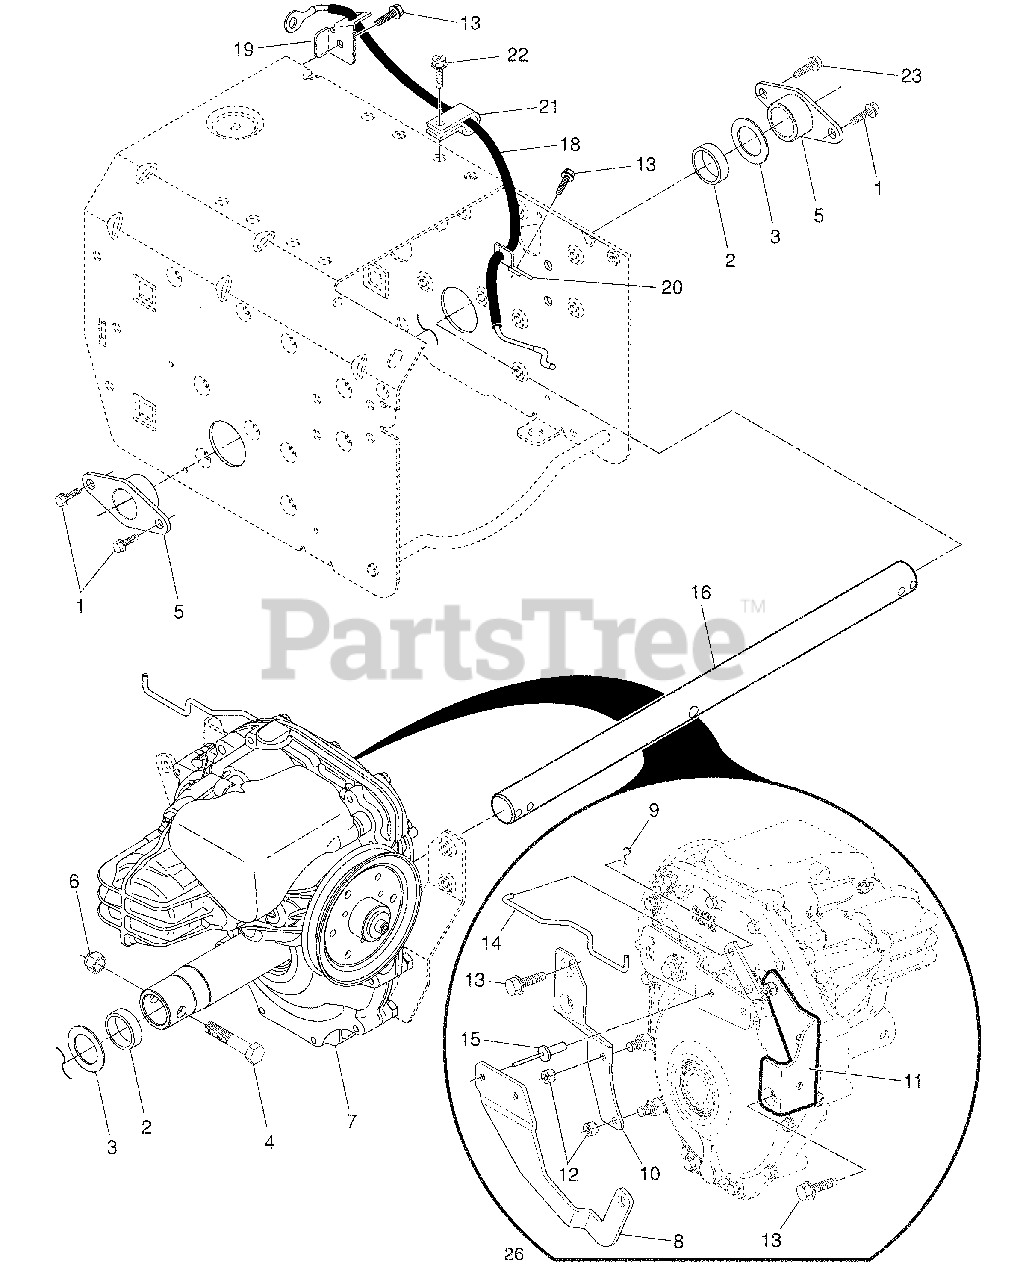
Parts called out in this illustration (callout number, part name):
1	Screw, Hex Head 5/16-18 x 3/4
2	Spacer, Axle
3	Washer, Thrust
4	Screw, Cap, Hex Head 3/8-16 x 2
5	Bearing, Axle
6	Nut, Hex, Centerlock 3/8-16
7	Transmission Assembly
8	Speed Control Arm, Hydro
9	Retainer Clip
10	Torque Strap
11	Bracket, Anti-Rotate
12	Nut, Hex, Nylock 1/4-20
13	Screw, Hex Washer Head 5/16-18 x 3/4
14	Rod, Bypass Valve
16	Shaft, Axle
18	Cable, Drive Control
19	Bracket, Cable, Rear
20	Bracket, Cable, Front
21	Clip, Cable
22	Screw, Slotted Hex Head 1/8 x 1/2
